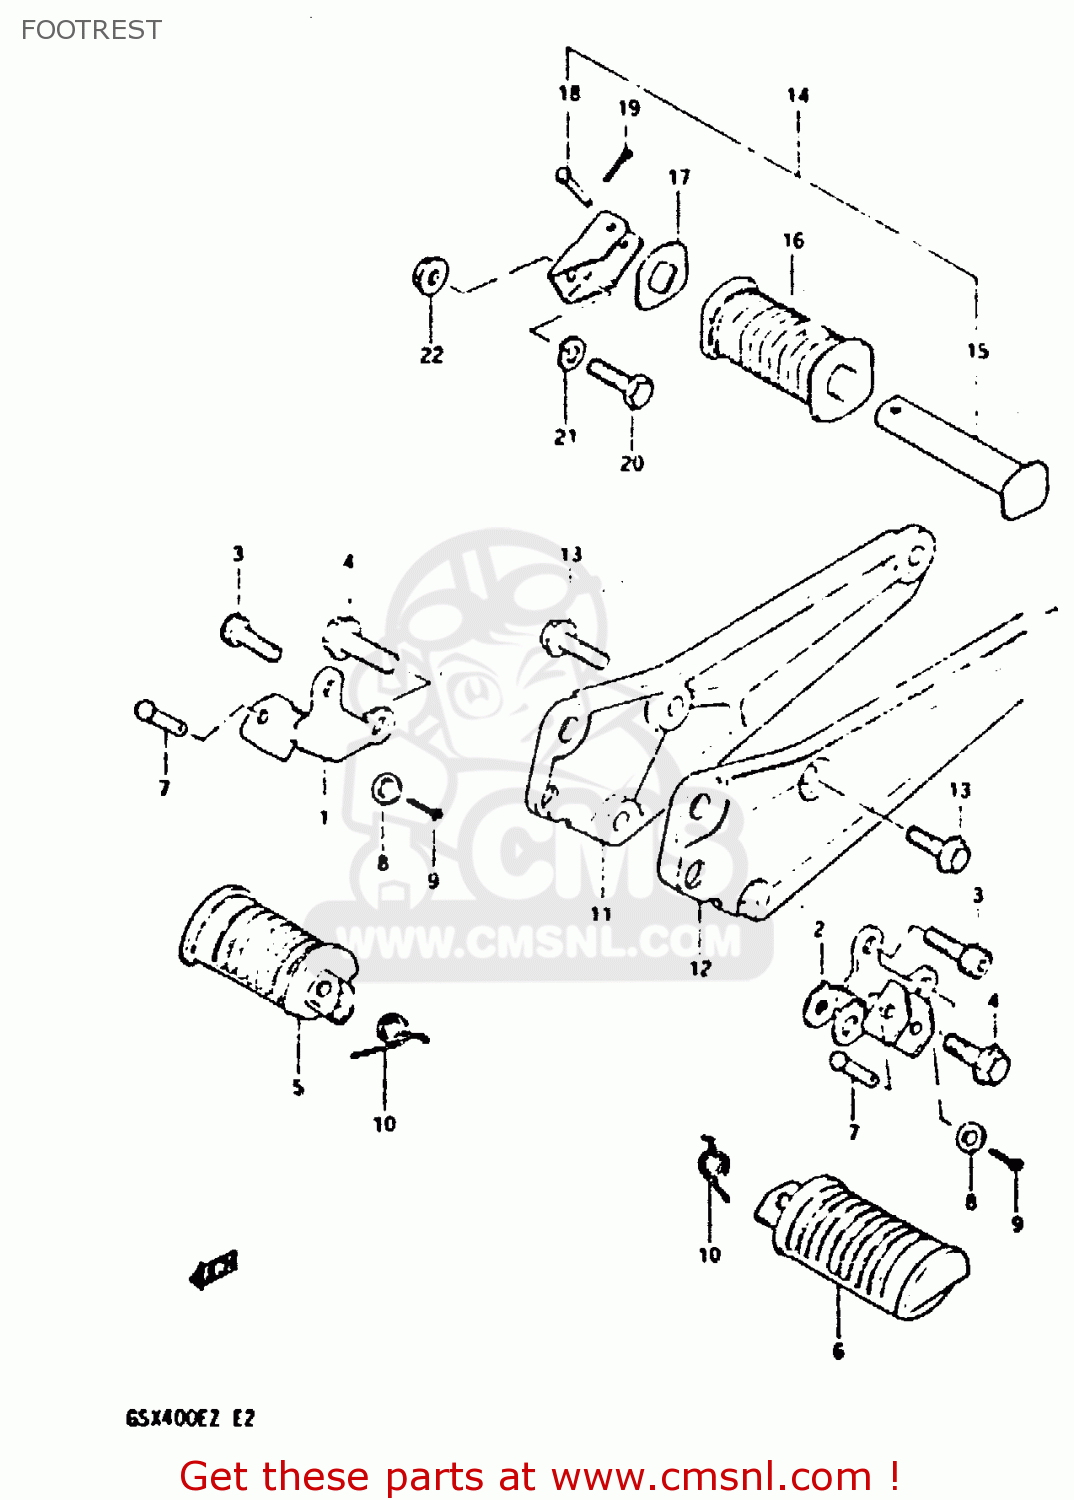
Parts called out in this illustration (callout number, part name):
1	BAR,FRONT FOOTREST
2	BAR,FRONT FOOTREST,LEFT
3	BOLT
4	BOLT
5	RUBBER,PILLION FOOTREST,R
6	RUBBER,PILLION FOOTREST,L
7	PIN
8	WASHER
9	PIN 20X20
10	SPRING
11	BRACKET,MUFFLER,RIGHT
12	BRACKET,MUFFLER,LEFT
13	BOLT
14	FOOTREST ASSY,PILLION,R
15	BAR,REAR FOOTREST,LEFT
16	RUBBER,PILLION FOOTREST
17	WASHER,FOOTREST RUBBER
18	PIN
19	PIN 20X20
20	BOLT,M10X1.25X
21	LOCK WASHER
22	NUT
